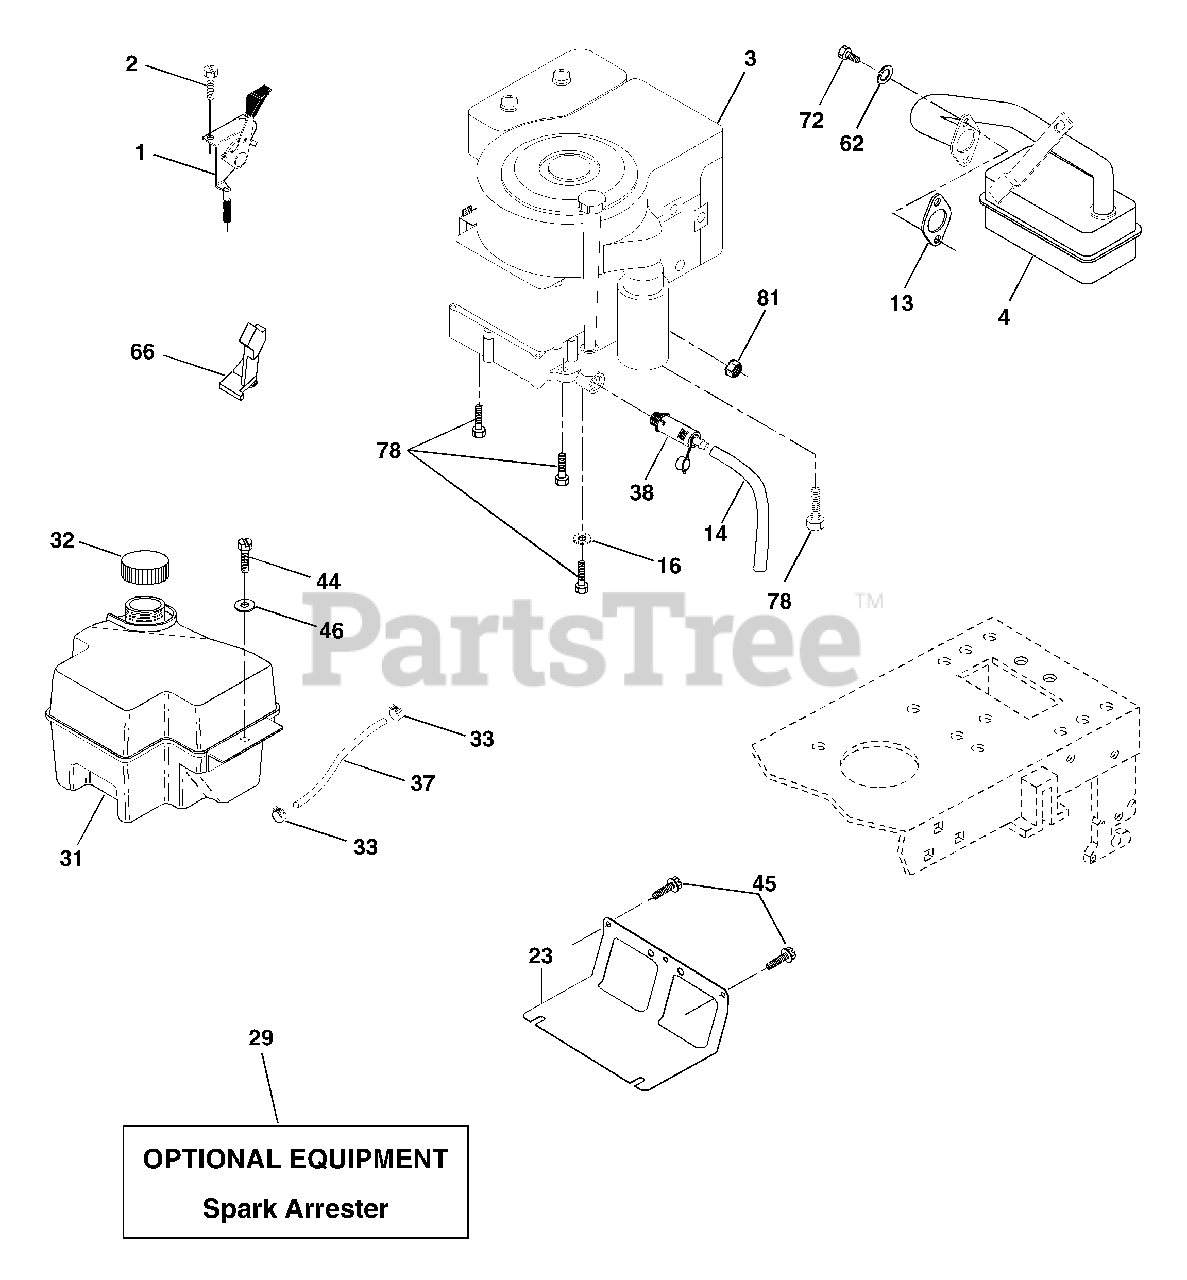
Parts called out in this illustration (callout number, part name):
1	Control Throt /Ch Flag
2	Screw Hex Thd Cut 1/4-20x5/8 T
4	Muffler Exhaust B&S Lt
13	Gasket 1 313 Id Tin Plated
14	Tube Drain Oil Easy
16	Washer Lock Ext Tooth 3/8
23	Shield Browning/Debris Guard
29	Arrestor Spark
31	Tank Fuel 2.00 Fr
32	Cap Asm Fule Top Vent N/Lany
33	Clamp Hose Blk
37	Line Fuel 20"
38	Plug Drain Oil Easy
44	Screw Hexwsh Thdrol 1/4-20 x 3/4
45	Screw Hexwsh Thdr 3/8-16 x 3/4
46	Washer 9/32 X 7/8 X 16ga
62	Washer Lock Hvy Hlcl Spr 5/16
66	Stop Throttle 3000 Rpm
72	Screw Hexhd Cap 5/16-18 x 3/4
78	Screw 3/8-16x1-1/4
81	Nut Keps 1/4-20 Unc
